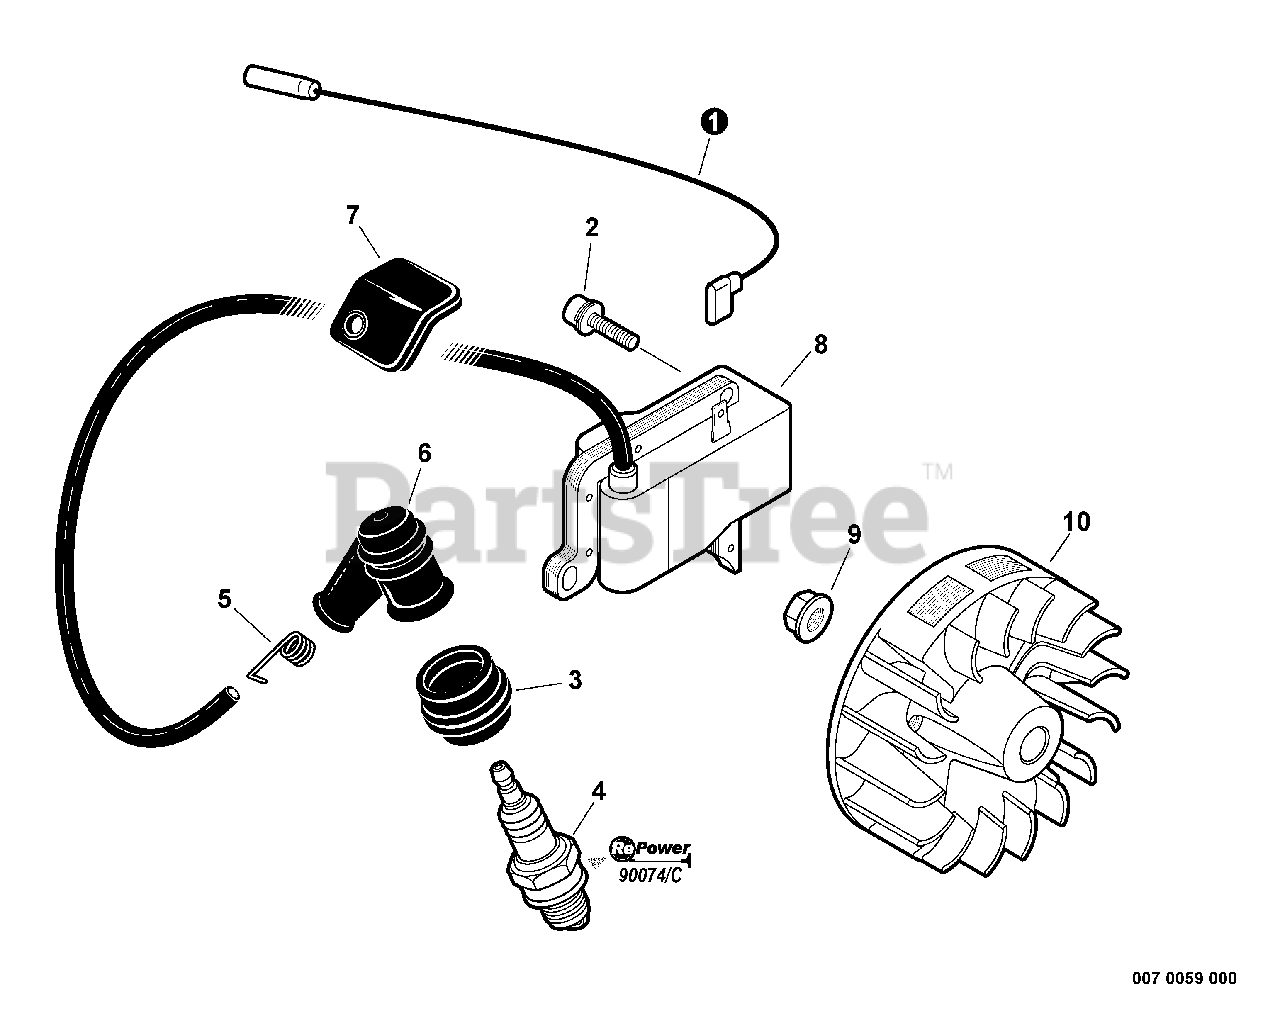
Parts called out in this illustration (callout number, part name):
1	LEAD - IGNITION 145 MM
2	BOLT 5×16
3	COVER, CAP
4	SPARK PLUG - BPM8Y
4	SPARK PLUG - BPMR8Y
5	TERMINAL, SPARK PLUG
6	CAP, SPARK PLUG
8	COIL, IGNITION
9	NUT, FLANGE M8
10	FLYWHEEL
11	TUNE-UP KIT - REPOWER
